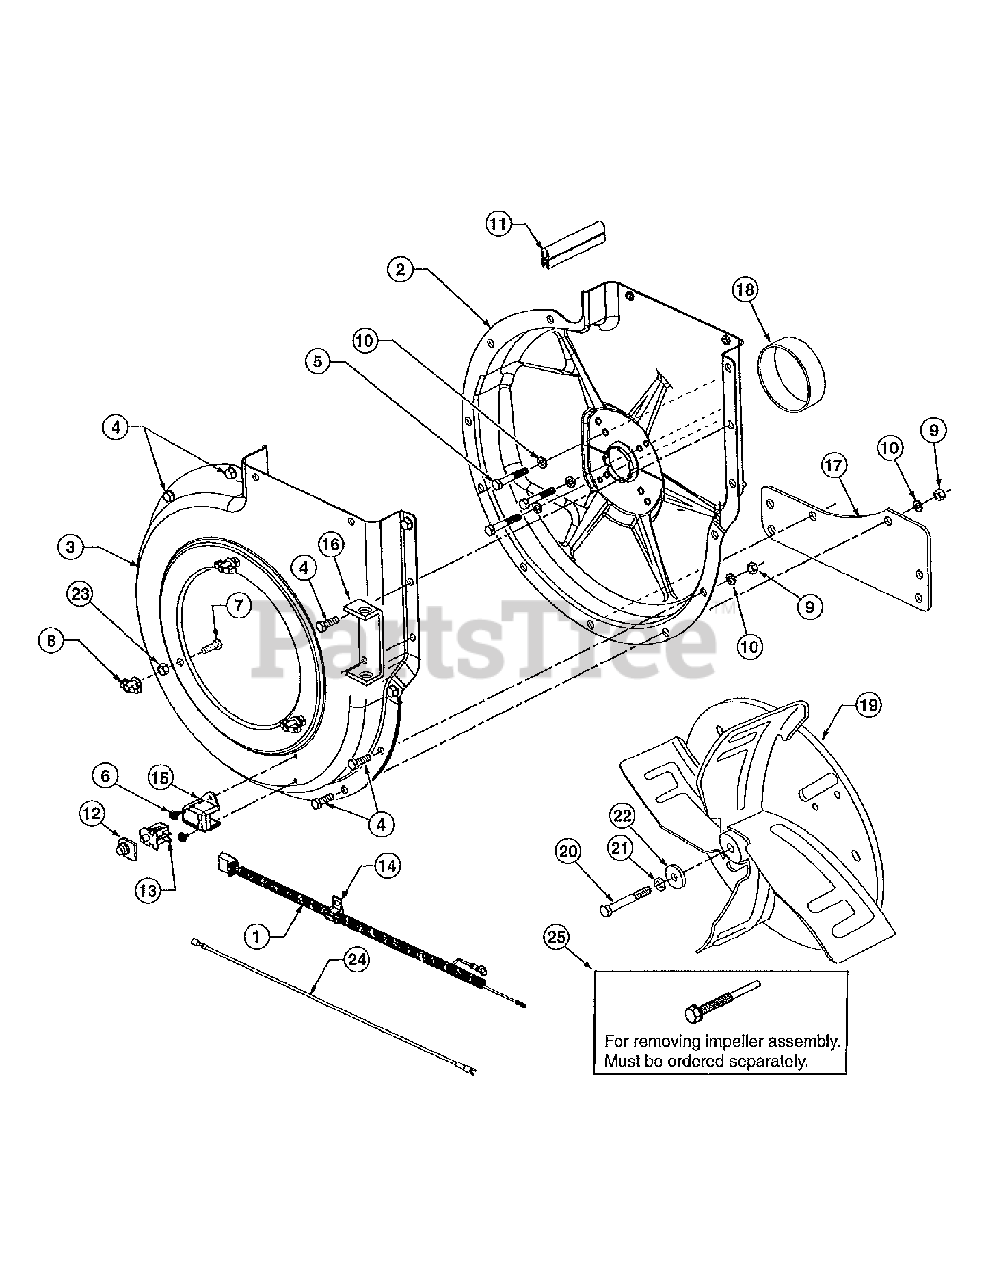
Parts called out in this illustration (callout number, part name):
1	Harness, Wire
2	Housing Ass'y. Inner
3	Housing Ass'y. Outer
4	Bolt, Hex 5/16-18 x 3/4"
5	Bolt, Hex 5/16-24 x 2"
6	Screw, SelfTap #10-16 x3/8"
7	Bolt, Hex 5/16-18 x 1"
9	Nut, Nylock Jam 5/16-18
10	Lock Washer, 5/16"
11	Seal, Rubber
12	Cover, Switch
13	Snap Mount Switch
15	Cover, Switch
16	Hose Hanger Bracket
17	Spacer, Housing
18	Adapter, Mounting
19	Impeller Assembly
20	Bolt, Hex 3/8-24 x 2-3/4"
21	Lockwasher, 3/8"
22	Flat Washer, 13/32" x 1-1/4"
23	Nut, 5/16-18
24	Harness Adapter
25	Impeller Service Tool
